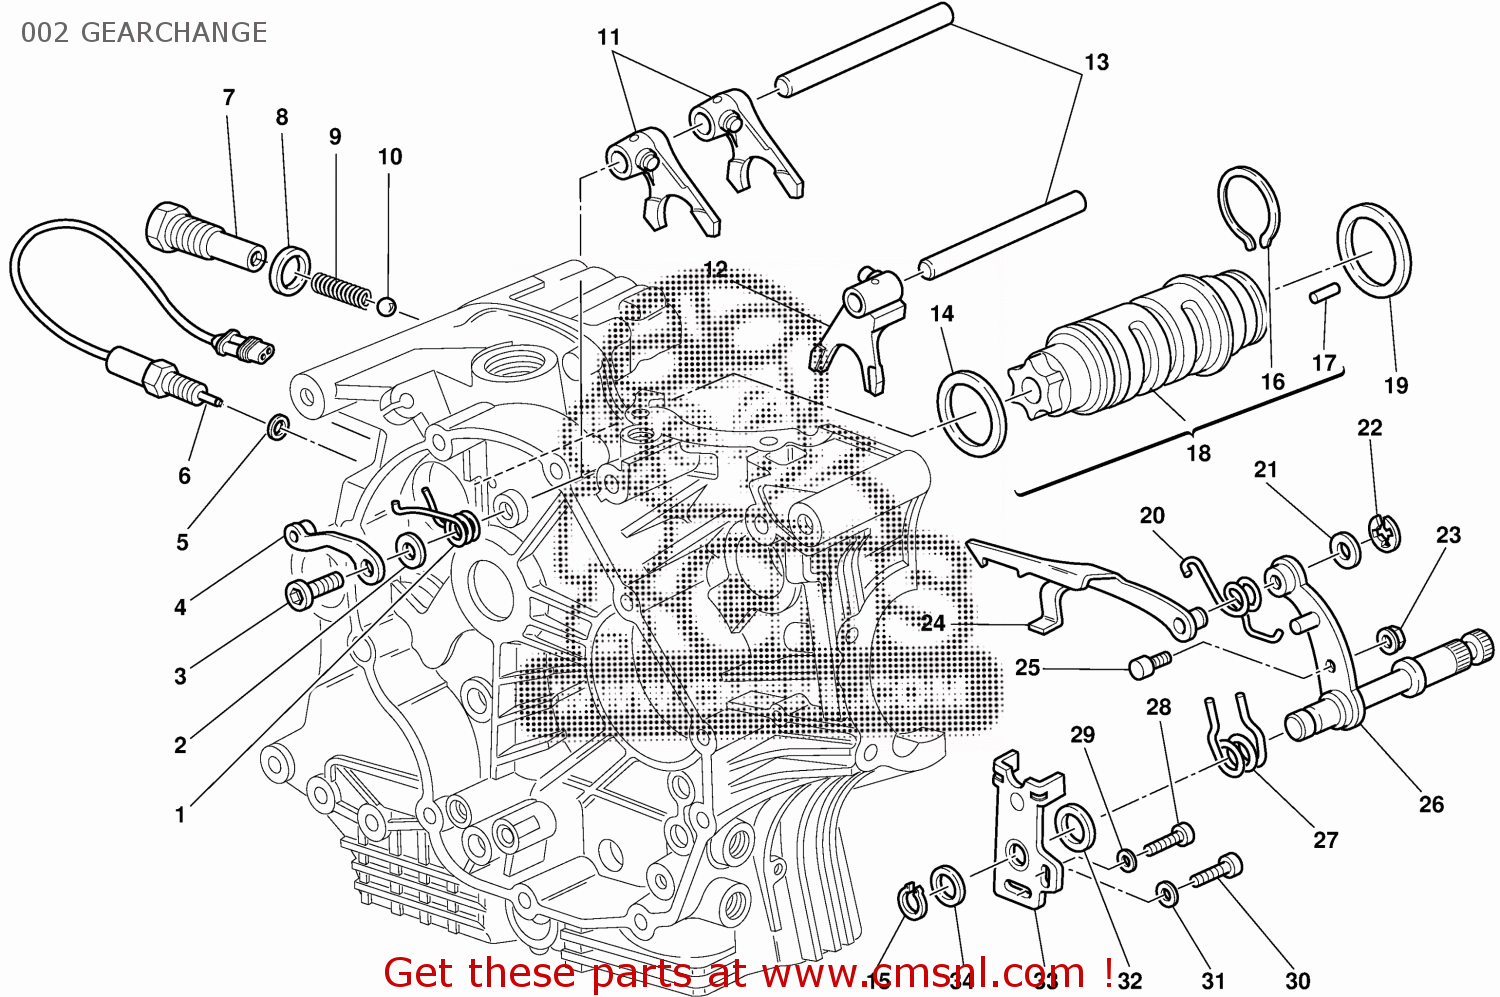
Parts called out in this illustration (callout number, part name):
1	SPRING, RETURN
2	WASHER 8.2X20X1
3	SCREW M8X21.5
4	GEAR FIXING CLICK ASSEMBLY
5	COPPER GASKET 11.9X8.2X2
6	NEUTRAL SWITCH ASSY
7	SCRE M16X1.5, SPRING SEAT
8	GASKET 16.2X24X2
9	GEAR SELECTOR SPRING
10	BALL 11MM
11	SHIFT FORK 1ST-4TH 2ND-3RD
12	SHIFT FORK 5TH-6TH
13	AXLE, GEAR SHIFT FORK 10X116 MM
14	THRUST WASHER 1 MM
15	CIRCLIP 15 DIN 471
16	NEEDLE RETAINING RING
17	SPECIAL ROLLER
18	CAM, GEAR SHIFT
19	THRUST WASHER 45.2X49X1.0
20	RETURN SPRING
21	THRUST WASHER 10.5X16X0.5
22	RING, BENZING 8MM DIN 6799
23	SELF LOCKING NUT M6 H5.5
24	CONTROL FORK
25	GEARCHANGE LEVER PIN
26	GEAR SELECTOR SHAFT
27	SPRING, SHIFT RETURN
28	BOLT, SOCKET HEAD M6X20
29	WASHER
30	SCREW TCEI M8X1.25X20
31	WASHER
32	CENTERING RING
33	STOPPER PLATE
34	THRUST WASHER 15.5X22X0.2
